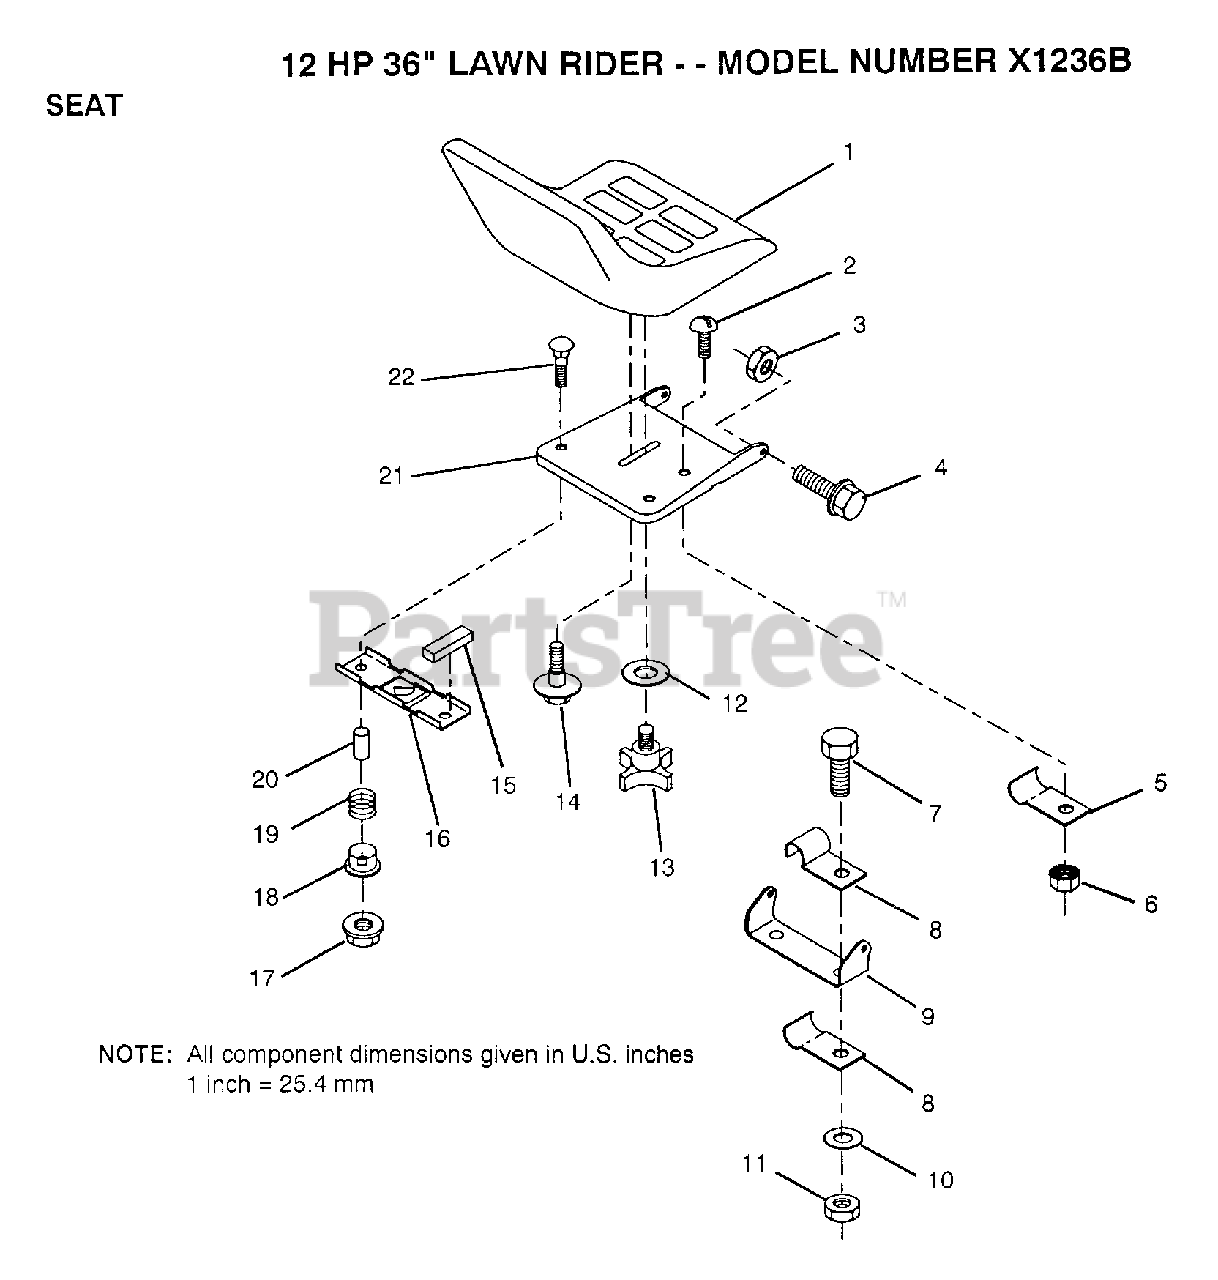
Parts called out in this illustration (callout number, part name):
6	"NUT,KEPS"
8	"CLIP,INSULATOR"
10	WASHER
12	WASHER
13	"KNOB 1/2"" YT"
14	"BOLT,SHOULDER"
15	STRIP FORM
16	BRKT SWITCH
18	BUSHING
19	SPRING
20	SPACER SPLIT
22	BOLT
